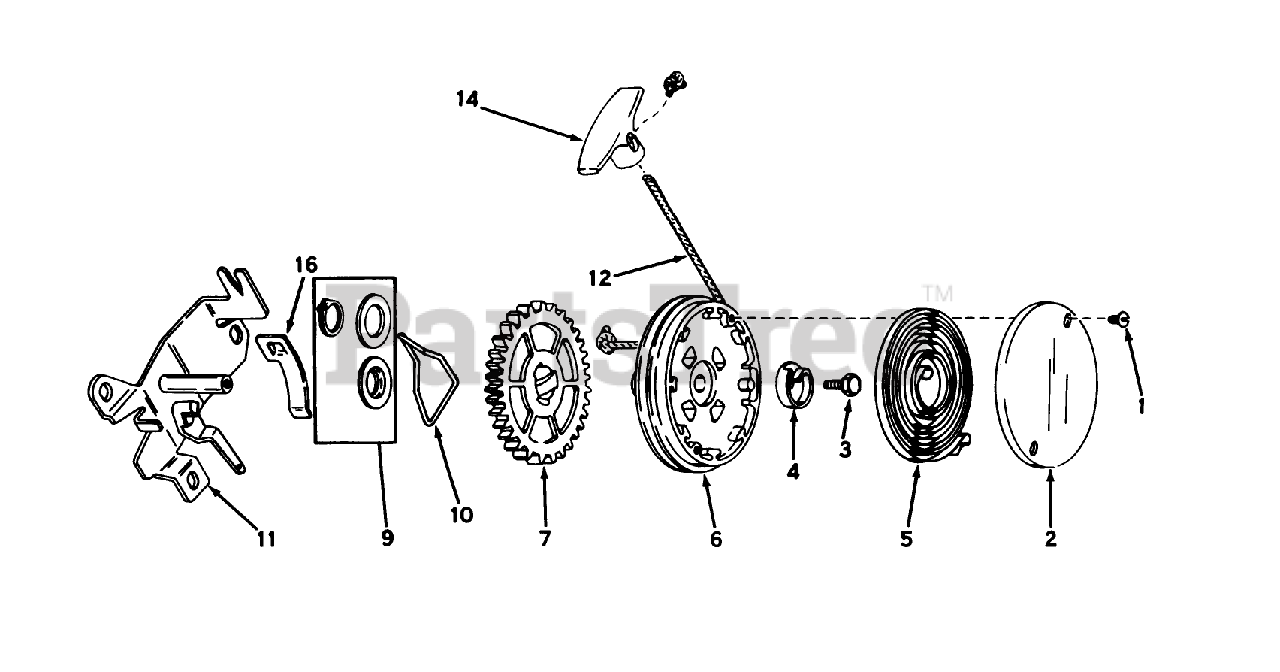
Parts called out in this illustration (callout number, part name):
2	Cover, Spring
3	Screw, Hex Washer Head
4	Hub Spring
5	Spring, Rewind
6	Pulley Assembly (Incl. Ref. #9)
9	Kit, Thrust Wash. & Snap Rg.
11	Bracket Assy., Mounting
12	Rope-Starter
14	Handle-Starter
16	Clip Rope
